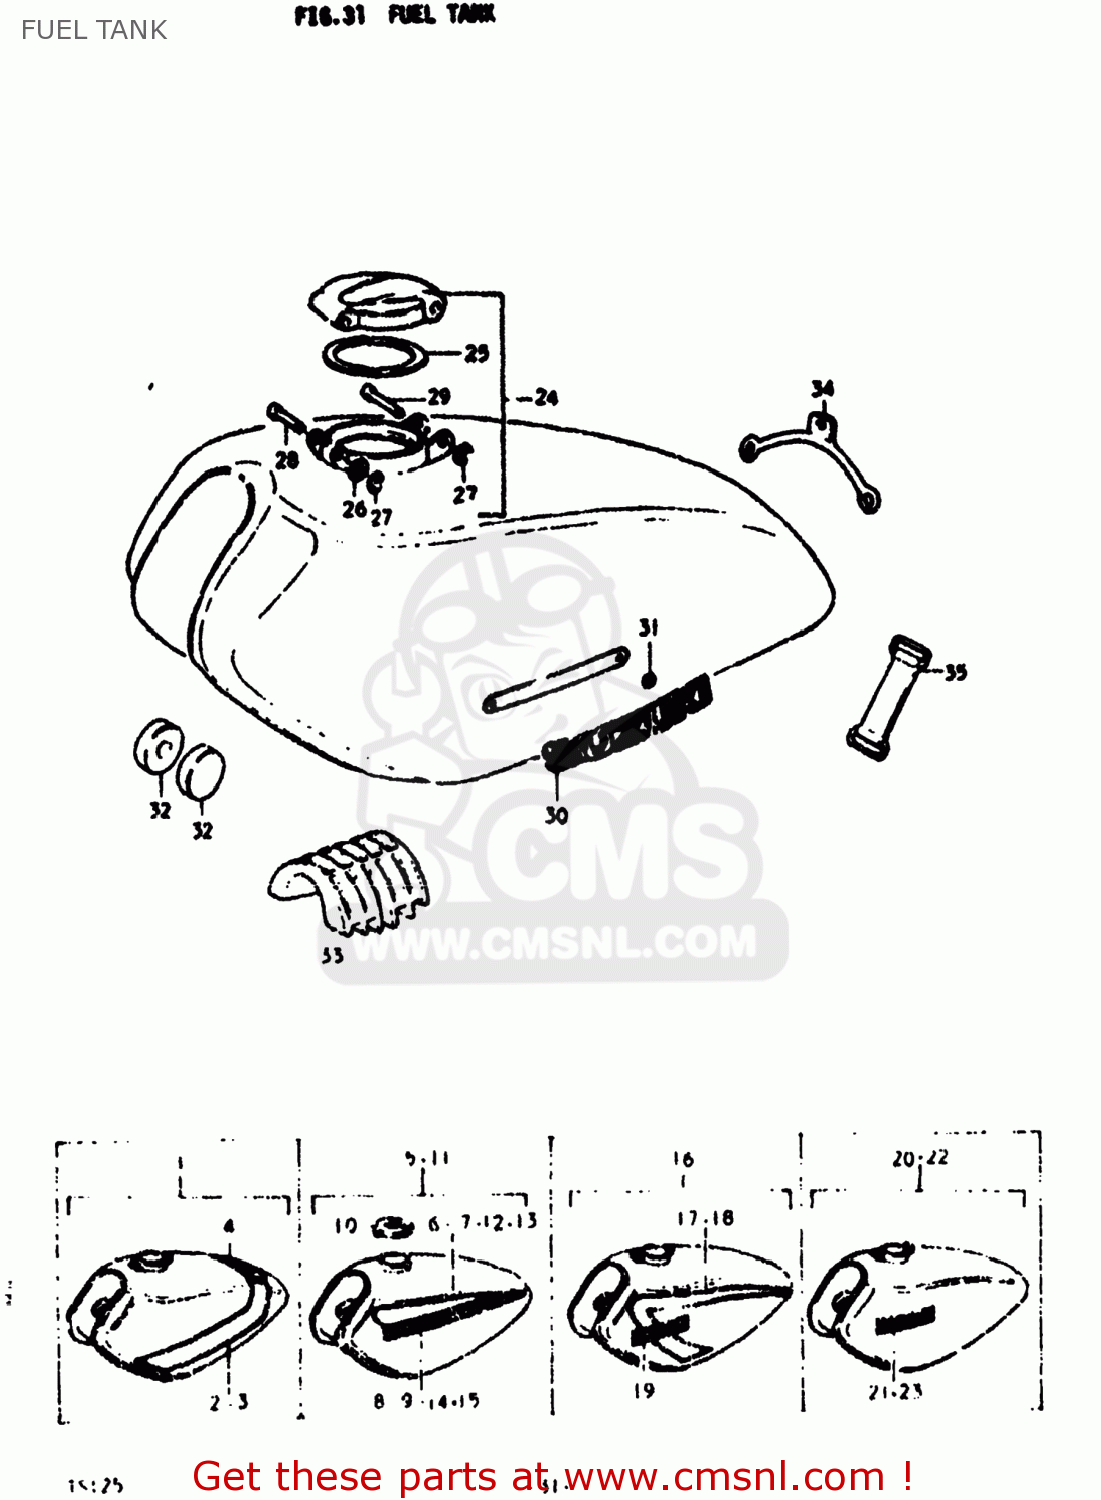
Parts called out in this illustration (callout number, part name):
1	TANK ASSEMBLY,FUEL
2	TAPE,FUEL TANK
3	TAPE,FUEL TANK
5	TANK ASSEMBLY,FUEL
6	TAPE,FUEL TANK
7	TAPE,FUEL TANK
8	EMBLEM
9	EMBLEM,FUEL TANK
10	CAP ASSEMBLY,FUEL TANK
11	TANK ASSEMBLY,FUEL
12	TAPE,FUEL TANK
13	TAPE,FUEL TANK
14	EMBLEM
15	EMBLEM,FUEL TANK
16	TANK ASSEMBLY,FUEL
17	TAPE,FUEL TANK
18	TAPE,FUEL TANK
19	EMBLEM
20	TANK ASSEMBLY,FUEL
21	EMBLEM A
22	TANK ASSEMBLY,FUEL
23	EMBLEM
24	CAP ASSEMBLY,FUEL TANK
25	GASKET (NAS)
26	WASHER
27	E RING
28	WASHER
29	PIN,FUEL TANK C
30	EMBLEM
31	NUT
32	CUSHION
33	CUSHION
34	BAND
35	BAND
